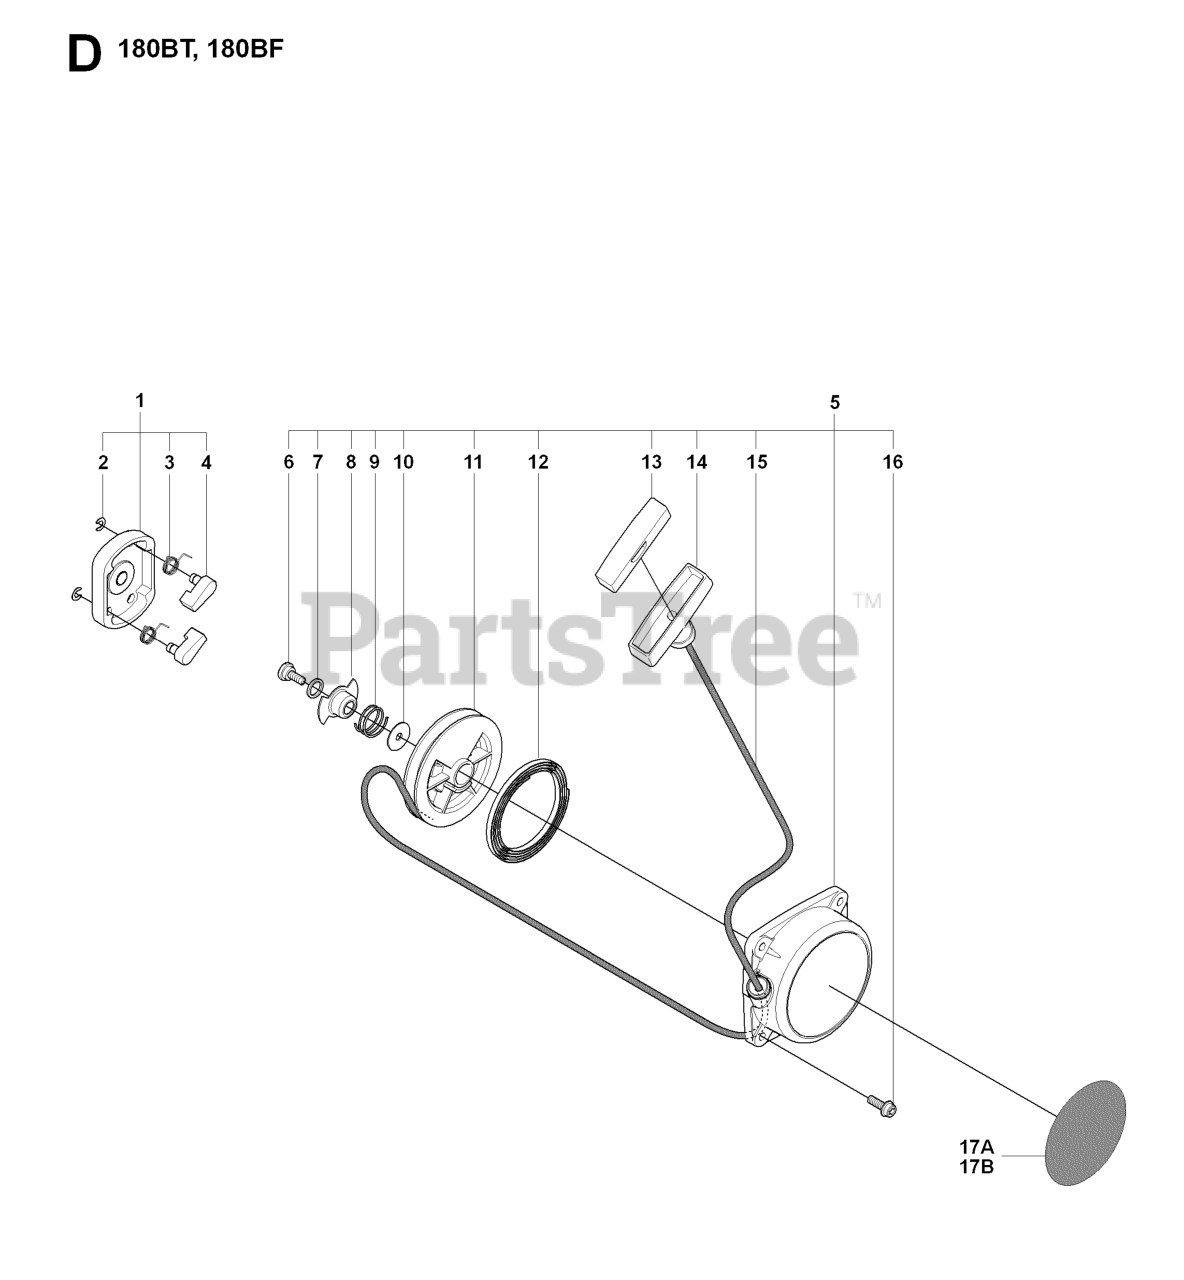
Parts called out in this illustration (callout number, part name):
1	STARTER PULLEY
2	E-RING
5	RECOIL
6	SCREW
7	WASHER
8	RP PLATE,FRICTION
9	SPRING,FRICTION
10	RP_WASHER
11	RP REEL
12	SPRING
13	RP_COVER
14	KNOB
16	BOLT
17A	LABEL RECOIL
17B	LABEL RECOIL
